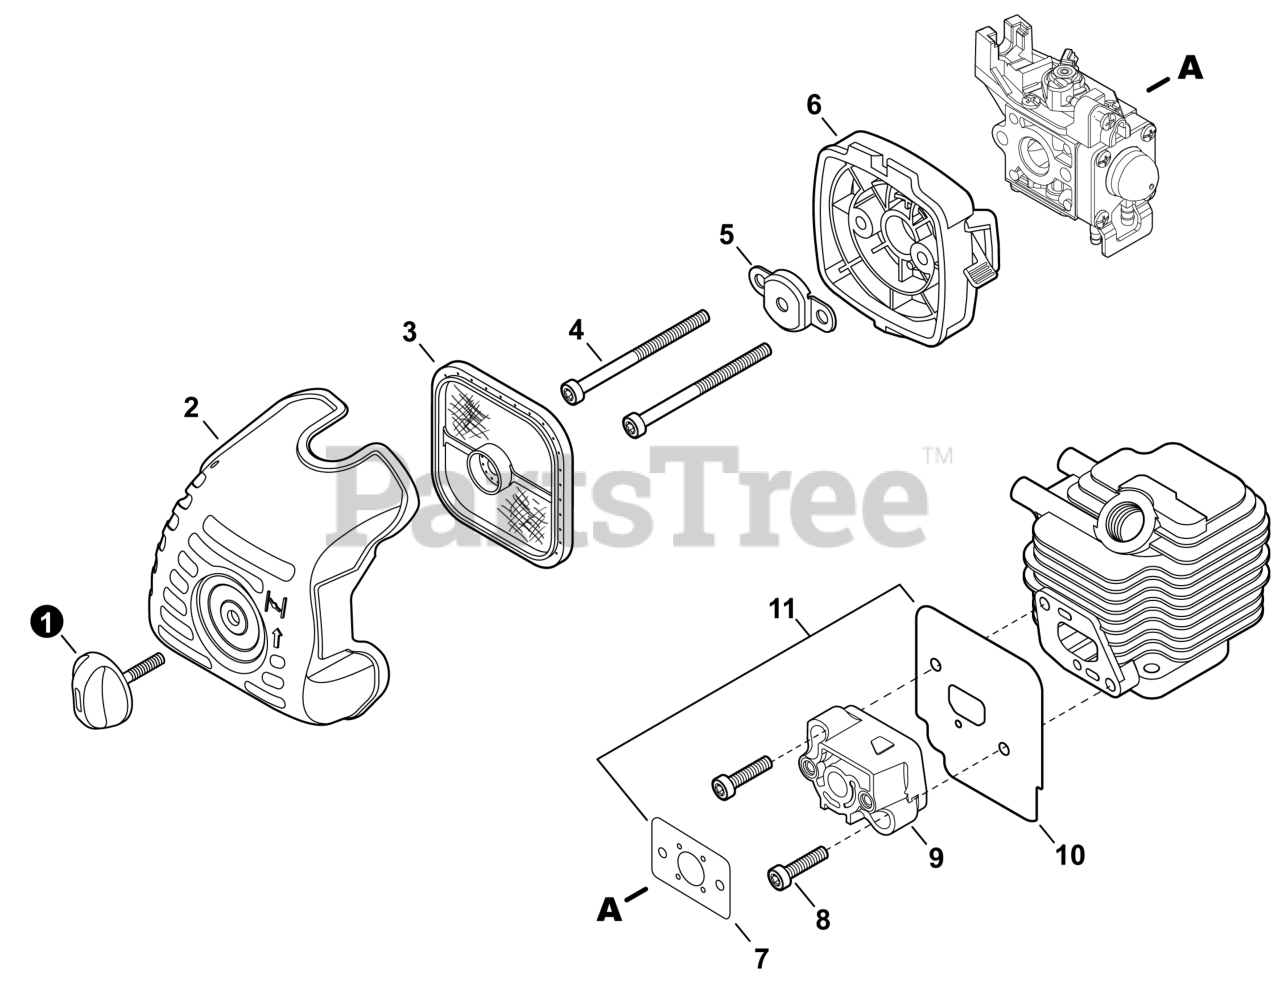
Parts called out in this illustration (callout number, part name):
1	THUMBSCREW
2	COVER, AIR FILTER
3	FILTER, AIR - DOUBLE LAYER
4	BOLT, TORX 5x55
5	PLATE, PREVENT
6	CASE ASSY, AIR FILTER
7	GASKET, INTAKE
8	BOLT, TORX 5x20
9	INSULATOR, INTAKE
10	HEAT SHIELD, INTAKE
11	GASKET KIT: ENGINE, INTAKE, EXHAUST
